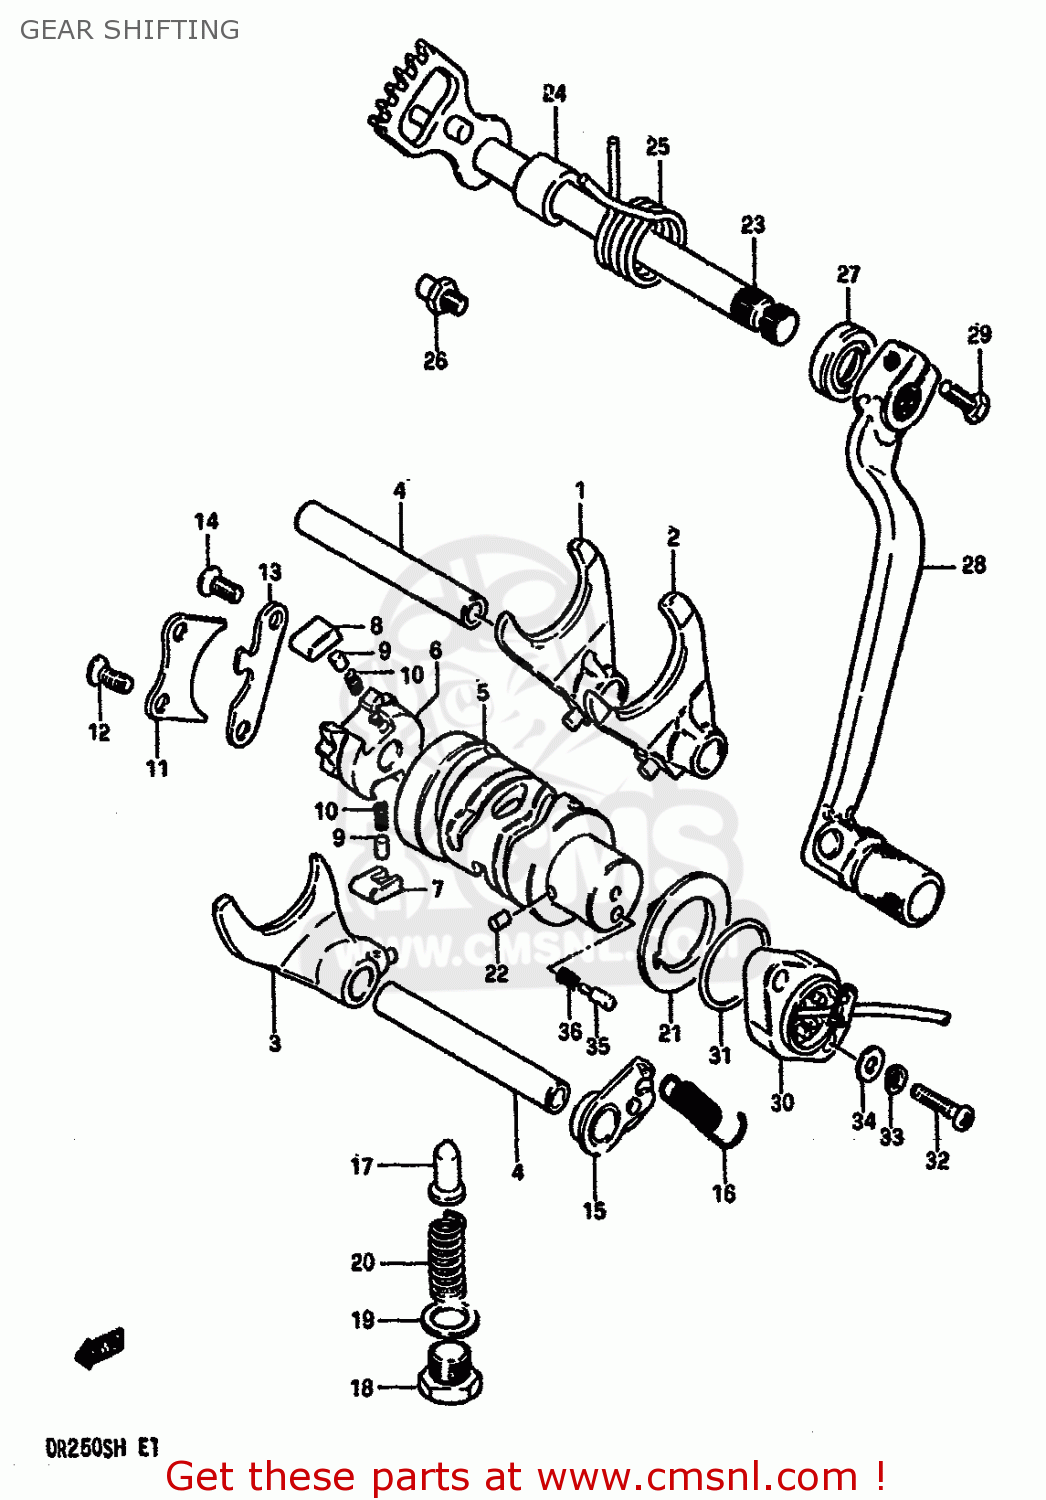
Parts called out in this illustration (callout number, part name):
1	FORK,GEAR SHIFT NO.1
2	FORK,GEAR SHIFT
3	FORK,GEAR SHIFT NO.3
4	SHAFT,GEAR SHIFT FORK
5	CAM,GEAR SHIFT
6	GEAR,GEARSHIFT CAM DRIVE
7	PAWL,GEAR SHIFT NO.1
8	PAWL,GEAR SHIFT NO.2
9	PIN(5X8)
10	SPRING
11	LIFTER,GEAR SHIFT POLE
12	SCREW
13	GUIDE,GEAR SHIFT CAM
14	SCREW
15	STOPPER,GEAR SHIFT CAM
16	SPRING
17	STOPPER,GEAR SHIFT CAM NO.2
18	PLUG (14X12)
19	GASKET(14X19.2X2) (NAS)
20	SPRING
21	PLATE,GEAR SHIFT CAM STOPPER
22	PIN 4X6
23	SHAFT,GEAR SHIFT
24	SPACER(12X20X15.3)
25	SPRING
26	STOPPER,GEAR SHIFT CAM
27	OIL SEAL
28	LEVER ASSY,GEAR SHIFT
29	BOLT
30	TERMINAL BASE,NEUTRAL SWITCH
31	O-RING (D:2.4 ID:26.2)
32	SCREW 5X20
33	LOCK WASHER
34	WASHER
35	PIN(5X15.5)
36	SPRING
